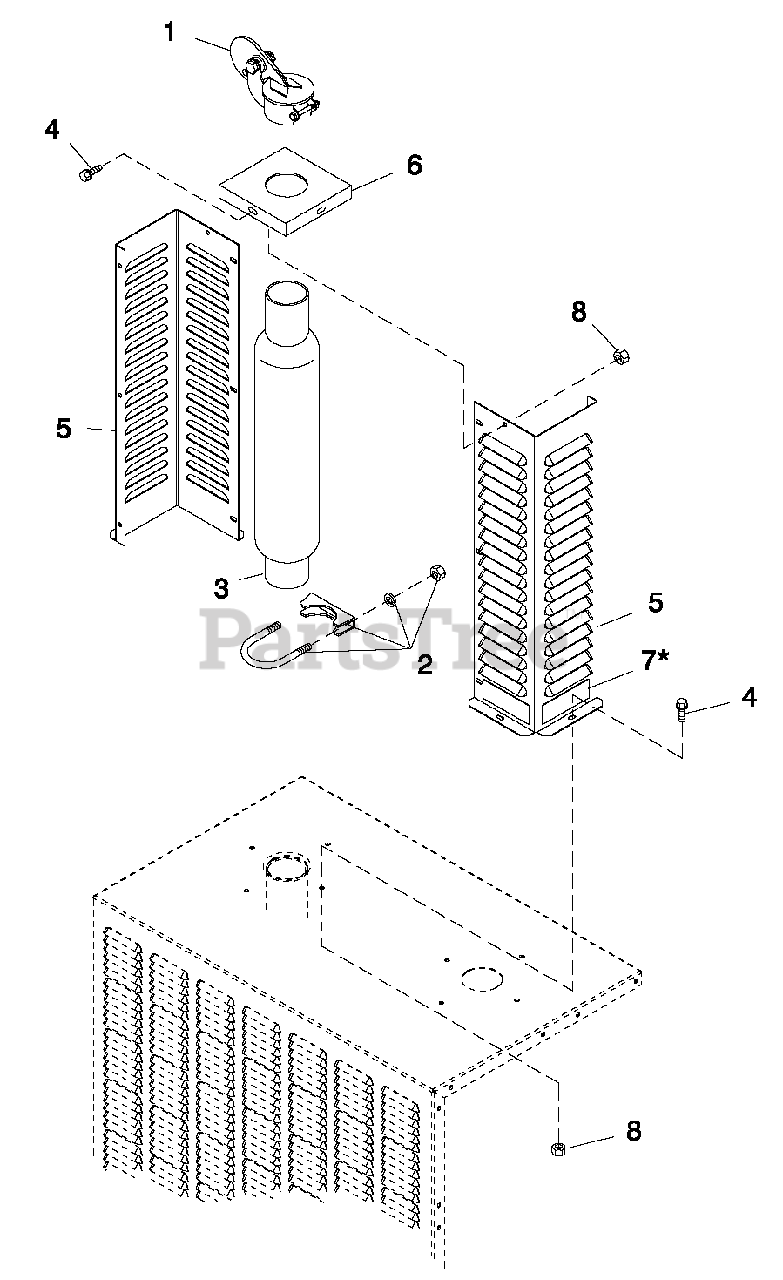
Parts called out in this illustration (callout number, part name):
1	RAIN CAP 2-1/2" AL
2	BOLT U 3/8-16 X 2.62
3	MFLR SEC 23.5"LG 2.5"IN/OUT
4	SCREW THF M6-1X16 N WA Z/JS
5	HEAT SHIELD EXHAUST STACK
6	CAP HEAT SHIELD EXHAUST STACK
7	DECAL WARNING HOT SURFACES BI
8	NUT HEX LOCK M6-1.0 SS NY INS
